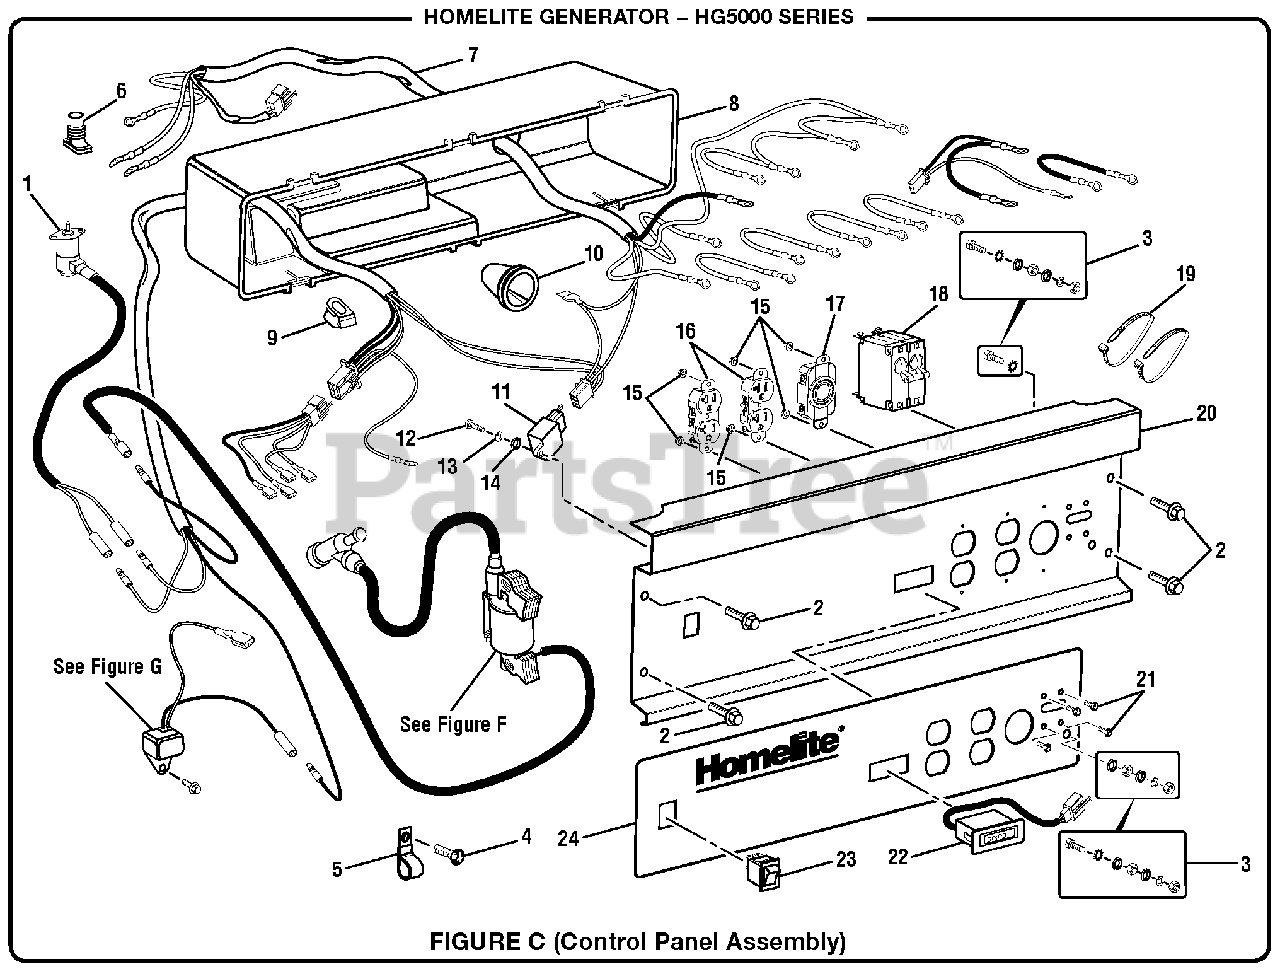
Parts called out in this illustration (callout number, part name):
1	Fuel Valve Solenoid
2	Bolt (M6 x 16 mm)
3	Ground Terminal Assembly
4	Screw (M6 x 12 mm)
5	Wire Clamp
6	Boot, Square
7	Wiring Harness Assembly
8	Cover, Control Panel Box
9	Boot Round, Switch Wire
10	Boot Round
11	Diode Assembly
12	Screw (M4 x 15 mm)
13	Lock Washer (M4)
14	Washer (M4)
15	Hex Nut (M4)
16	120 V/ 20amp Duplex Receptacle
17	220 V/ 30amp Twist Lock Receptacle
18	Circuit Breaker, 2 pole 25 amp
20	Control Panel
21	Screw (M3 x 6 mm)
23	Ignition Switch
24	Control Panel Label
